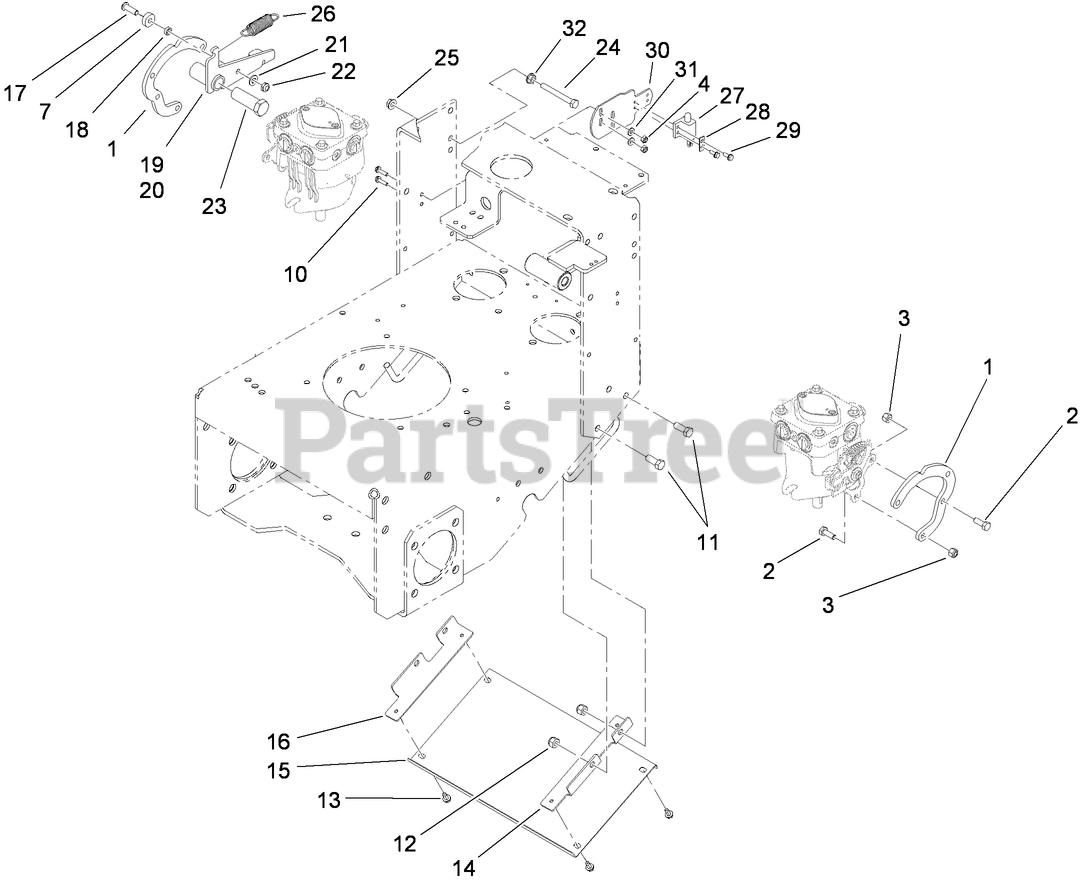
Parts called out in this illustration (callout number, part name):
1	BRACKET-ADAPTER, PUMP
2	SCREW-HH
3	NUT-LOCK, NI
4	NUT-LOCK, NI
7	BEARING-BALL
10	SCREW-HWH
11	SCREW-HH
12	NUT-LOCK, NI
13	SCREW
14	ANGLE-MOUNTING, LEFT
15	PANEL-BOTTOM
16	ANGLE-MOUNTING, RIGHT
17	SCREW-HSBH
18	SPACER-BEARING
19	RH DETENT ARM ASM
20	LH DETENT ARM ASM
21	WASHER-PLAIN
22	NUT-LOCK, NI
23	PIN-ADJUSTMENT, NEUTRAL
24	SCREW-HH
25	NUT-HF
26	SPRING-EXTENSION
27	SWITCH-CLOSED, NORMALLY
28	PLATE-SWITCH
29	SCREW-TAPTITE
30	BRACKET-NEUTRAL
31	WASHER-FLAT
32	NUT-HHF, SMOOTH
